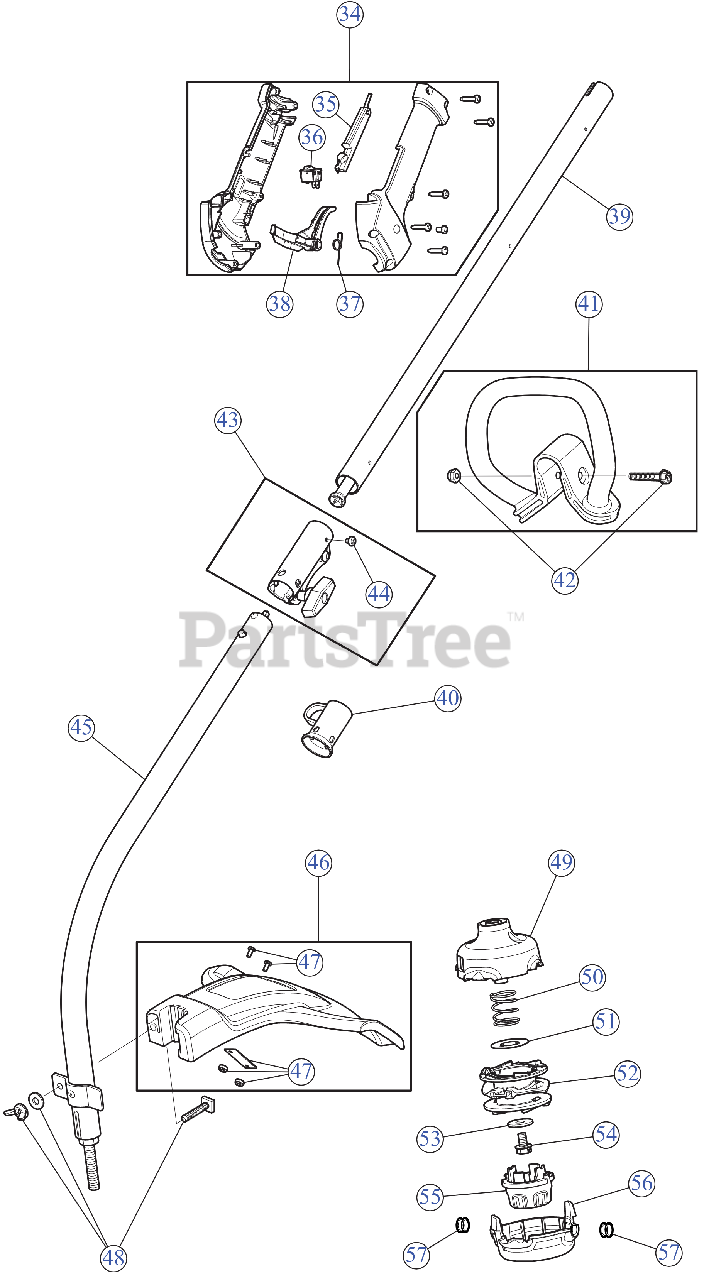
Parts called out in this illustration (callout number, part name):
34	THROTTLE GRIP ASSEMBLY
35	LEVER LOCK OUT
36	SW, MOMENTARY ON/O
37	SPRING TRIG
38	THROTTLE TRIGGER
39	BOOM ASSEMBLY UPR
40	HANGER
41	D-HANDLE
42	BOLT 1/4-20X1 1/2
43	COUPLER ASSEMBLY
44	SCREW, 10-32X.250 TA
45	BOOM ASM LWR
46	GUARD ASSEMBLY
47	ASSEMBLY, BLADE
48	BLADE GUARD MOUNTING HARDWARE
49	OUTER SPOOL 2N1
50	SPRING-SPOOL
51	STAMPED COVER
52	INNER REEL 2N1
53	FLAT WASHER 1.0 OD:.331 ID
54	BOLT 5/16-18
55	BUMP KNOB
56	CAP 2N1
57	EYELET
